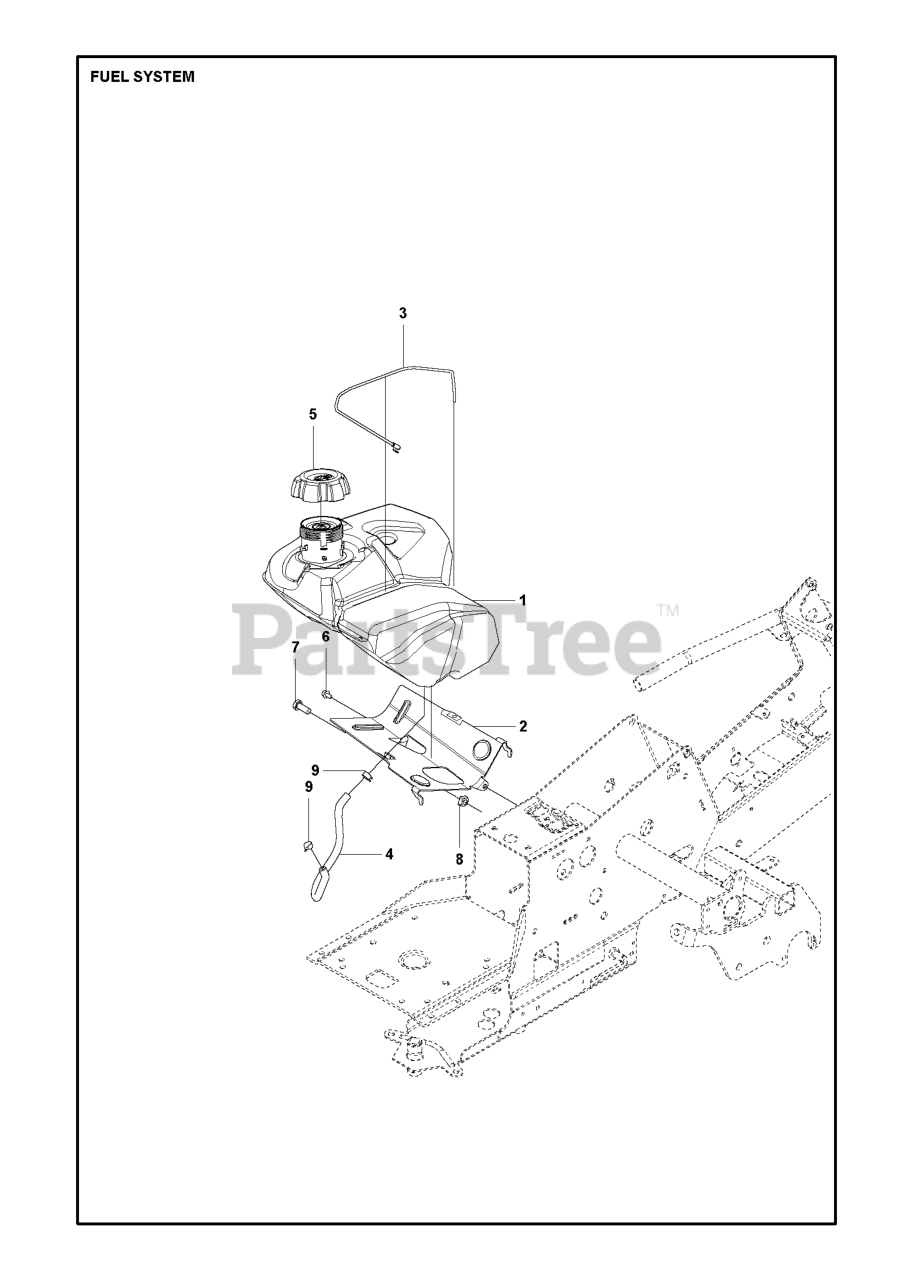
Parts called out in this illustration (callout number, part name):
5	CAP.ASSY.FUEL.3".N-EPA.GRY.498
7	Screw M10x25
8	LOCKNUT M6
